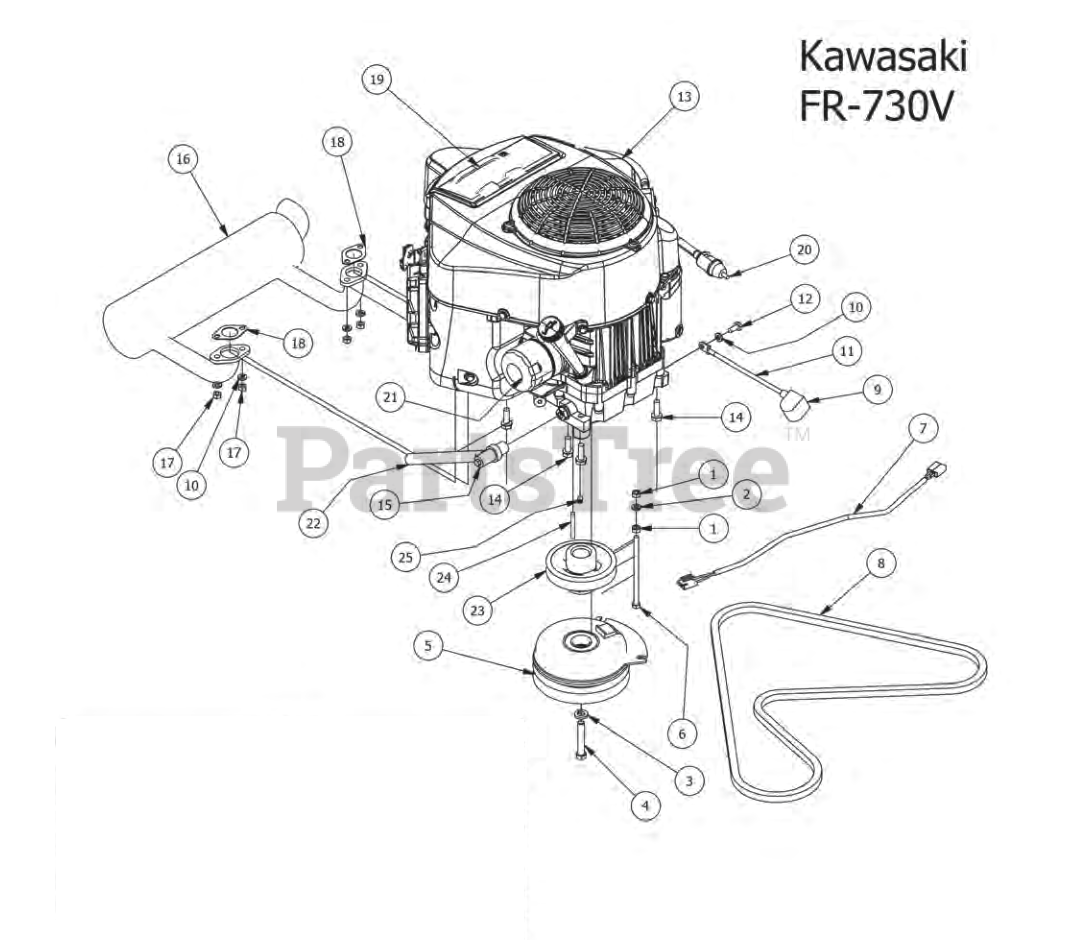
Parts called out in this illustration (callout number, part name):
2	5/16" Lock Washer
3	7/16" Lock Washer
4	7/16" x 2 1/2" Hex Bolt
5	Clutch Assembly
6	5/16-18 x 5-1/2 GR 5 Hex Bolt
7	Clutch Pigtail
9	Black Boot For ground cable
10	5/16" Lock Washer
11	Starter to chassis cable
12	M8x1.20x20MM Hex head bolt
13	FR 730V-S16 Kawasaki Engine 1.125" shaft-ZT
14	3/8 x 1 1/8 bolt
16	Exhaust Kawasaki FS/FR-ZT/CZT
17	M8-1.25 Zinc Nut
18	Exhaust gasket
19	Kaw air Filter For Engine
20	Universal Inline Fuel Filter
21	Oil Filter
22	1/2 Clear Braded Hose Priced/Foot
23	4.3/4 Motor Pulley
24	1/4 x 2 Square key Stock
25	5/16 Set Screw
